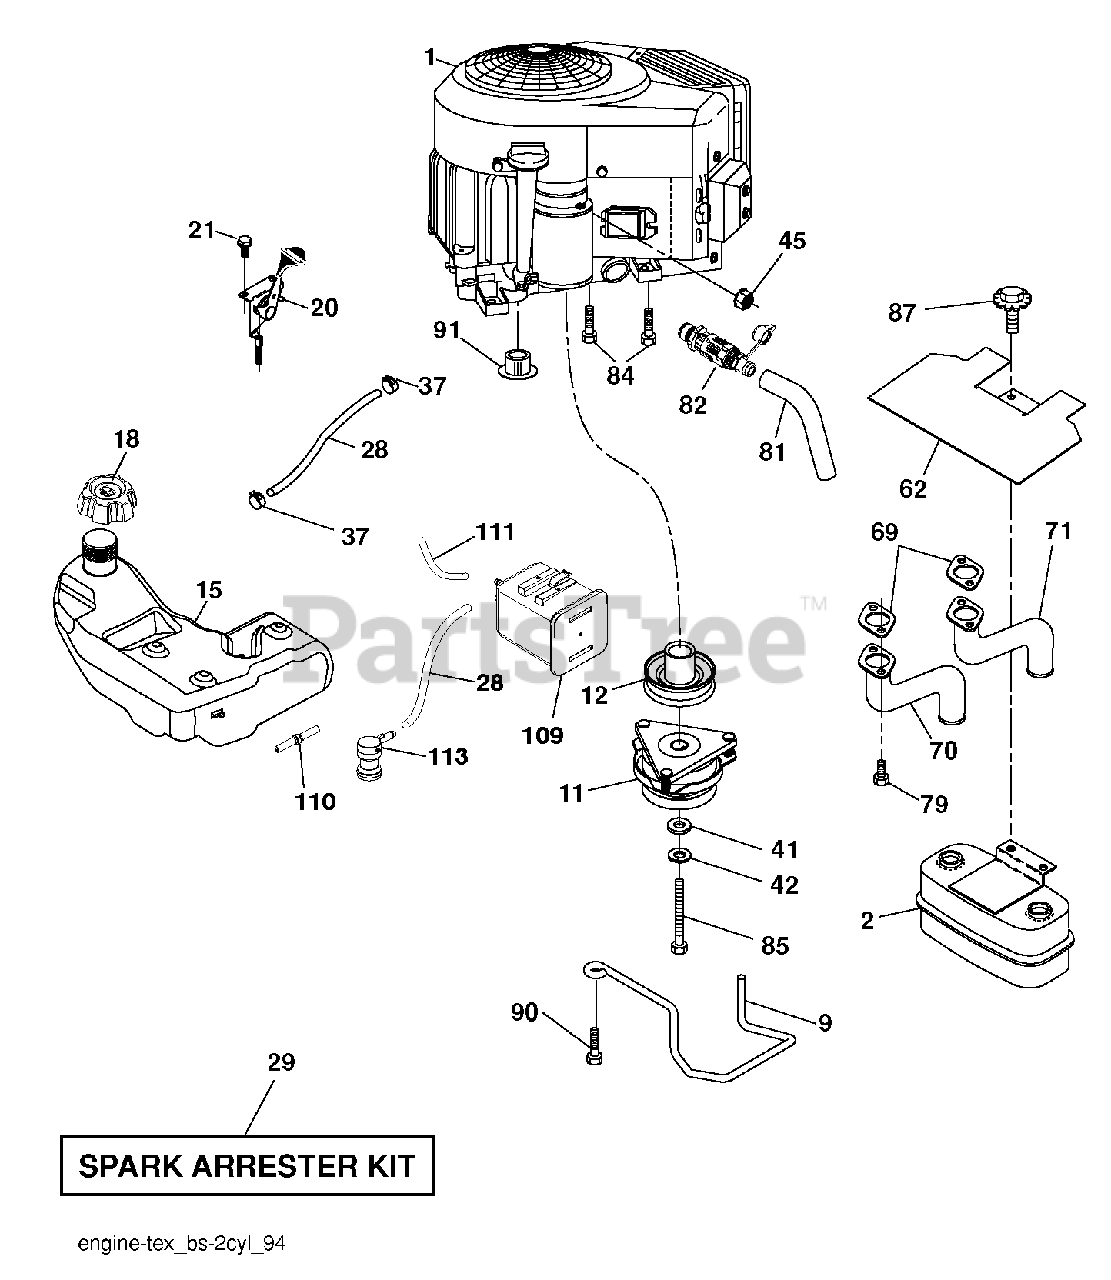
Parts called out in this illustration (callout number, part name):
2	MUFFLER.ASM.TWN.EXTNDED.DFLCTR
9	KEEPER BELT ENGINE
11	CLUTCH.ELECTRIC.LT.48"*
12	PULLEY.ENGINE.TUFFTORQ
15	TANK.ASM.FUEL.3GA.CARB
18	CAP.ASM.FL.RITCH.3"E10.SYM.498
20	CONTROL.TH/CK.COBRA.B&S.TWN.
21	SCREW.#10 X 0.750.BOS
28	LINE.FUEL.64"REAR.EMIS
29	KIT.SPARK ARRESTOR 794945 B&S
37	HOSE CLAMP
42	LOCKWASHER
45	NUT
62	SHIELD.HEAT.MUFFLER
69	GASKET.MUFFLER
70	EXHAUST.TUBE.LH.BS/TWIN
71	EXHAUST.TUBE.RH.B&S.TWIN.INTEK
79	SCREW.SOCKET.HEAD.5/16-18
81	TUBE, DRAIN OIL ASM.
82	VALUE.OIL.DRAIN
84	SCREW.3/8-16
85	BOLT HEX 7/16-20X4-1/4"
87	Bolt, 5/16-18 X 1-3/4
90	SCREW 3/8-16X1
91	BUSHING.1.375OD
109	CANNISTER, CARBON
110	VALVE.ASM.ANTI-SLOSH
111	RP PURGE LINE
113	VALVE.SLANT.CARTRDG.90 DEG.TEX
